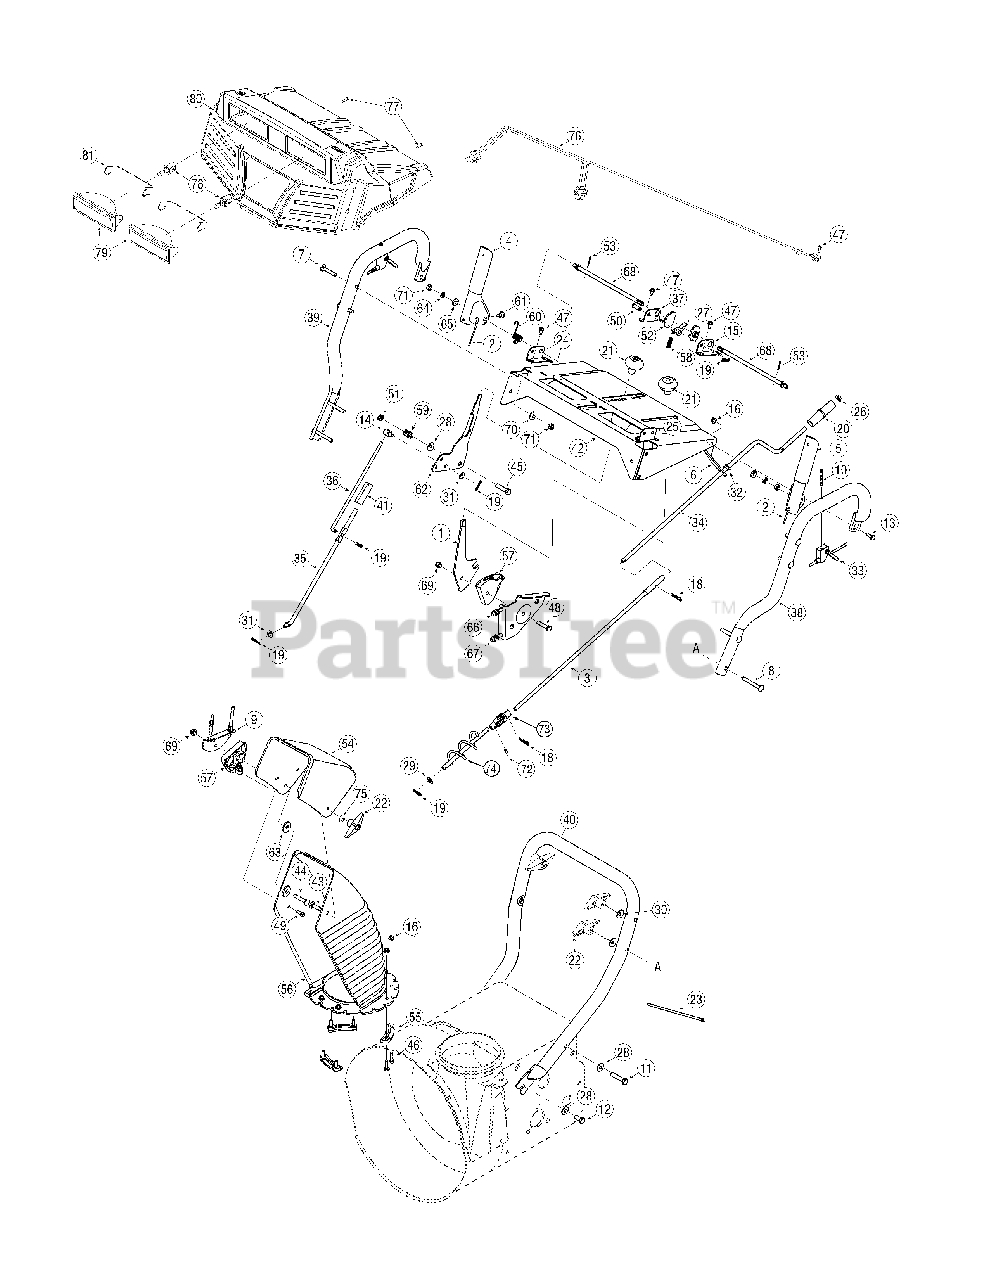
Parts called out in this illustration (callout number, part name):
1	Chute Tilt Handle
2	Cable Ass’y (Auger/Drive)
4	Engagement Handle RH Black
5	Engagement Handle LH Black
6	Upper Chute Crank Support
7	Carriage Bolt 5/16-18 x 1.75" Lg.
8	Carriage Bolt 5/16-18 X 2.50
10	Screw, #10-24 x 1.75
11	Hex Screw 3/8-16 x 2.0 Gr. 5
12	Hex TT Screw 3/8-16 x .75
13	Hex Cap Bolt 1/4-20 x .75" Lg.
14	Adjustment Ferrule
15	LH Handle Support Brkt. 5/8"
16	Hex L-Flanged Nut 1/4-20 Gr. F Nylon
18	Internal Cotter Pin
19	Int. Cotter Pin .072 x 1.13" Lg.
20	Knob 1.0 x 3.2
21	Shift Knob
23	Cable Tie
24	RH Handle Support Brkt. 3/8"
26	Push Nut 3/8" Rod
27	Cam Lock Pawl
28	Cupped Washer .375 ID x .870 OD x .063
29	Flat Washer .406" I.D. x .75" O.D.
30	Cupped Washer .345 ID x .88 OD x .06
31	Flat Washer .34 ID x .688 OD x .065
32	Plastic Bushing .380 ID
33	Steering Trigger
34	Upper Chute Crank Assembly
35	Lower Shift Rod
36	Upper Shift Rod
37	RH Handle Support Brkt. 5/8"
38	Upper Handle LH - Black
39	Upper Handle RH - Black
40	Lower Handle - Black
41	Connector - Shift Rod
42	Handle Panel Support Ass’y - Cub Yellow
43	Carriage Bolt 5/16-18 x 1.00" Lg
44	Carriage Bolt 5/16-18 x 1.75" Lg.
45	Hex Scr 3/8-24 x 1.50
46	Screw 1/4-20 x 1.0
47	Hex Wash S-Tapp Scr 1/4-20 x .50
48	Hex Bolt 5/16-18 x 1,50" Lg. Gr. 5
49	Hex Tapp Scr 1/4 x .75" Lg.
50	Clevis Pin .31 Dia. x 1.0" Lg.
51	Hex Nut 3/8-16 Gr. 5 Nylon
52	Cam Handle Lock
53	Cotter Pin 3/32 x .75
54	Upper Chute
55	Chute Flange Keeper
56	Lower Chute
57	Cable Guide
58	Compression Spring .62 OD x 6.12" Lg.
59	Compression Spring .38 ID x .88 Lg
60	Torsion Spring
61	Rubber Bumper
63	Flat Washer .344 ID x 1.125 OD x .125
64	L-Wash 5/16 ID
65	Flat Washer (special) .350 sq. x .72 x .134
66	Chute Control Cable 66"
67	Chute Control Cable w/clip
69	Hex L-Flanged Nut 5/16-18 Gr. F Nylon
70	Flat Washer .349 ID x .879 OD x .063
71	Hex Patch L-Nut 5/16-18
72	Spiral Pin .156 Diam x .80" Lg.
73	Joint Block Ass'y
74	Chute Crank Assembly
75	Flat Washer .349 ID x .879 OD x .063
76	Wire Harness
77	Hex Tapp Wash Hd. Scr. #10 x 5/8
78	Bulb #890, 12 V, 27 Watt
79	Head light Housing
80	Black Handle Panel
